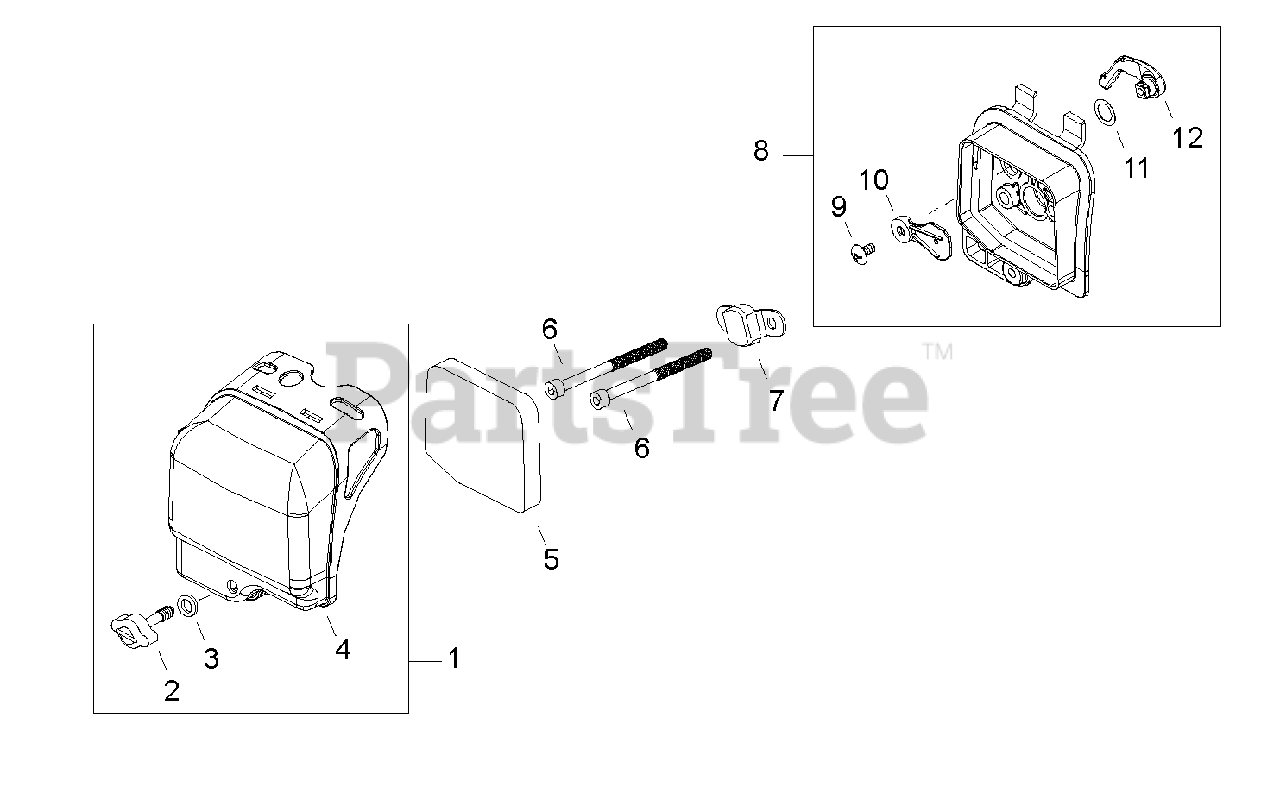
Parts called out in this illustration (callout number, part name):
1	COVER ASSY, AIR FILTER
2	THUMBSCREW
3	WASHER 5
4	COVER, AIR FILTER
5	FILTER, AIR
6	BOLT M5×60
7	BRACKET
8	CASE ASSY, AIR FILTER
9	SCREW, TRUSS M4×12
10	PLATE, CHOKE
11	WASHER, WAVE
12	LEVER, CHOKE
